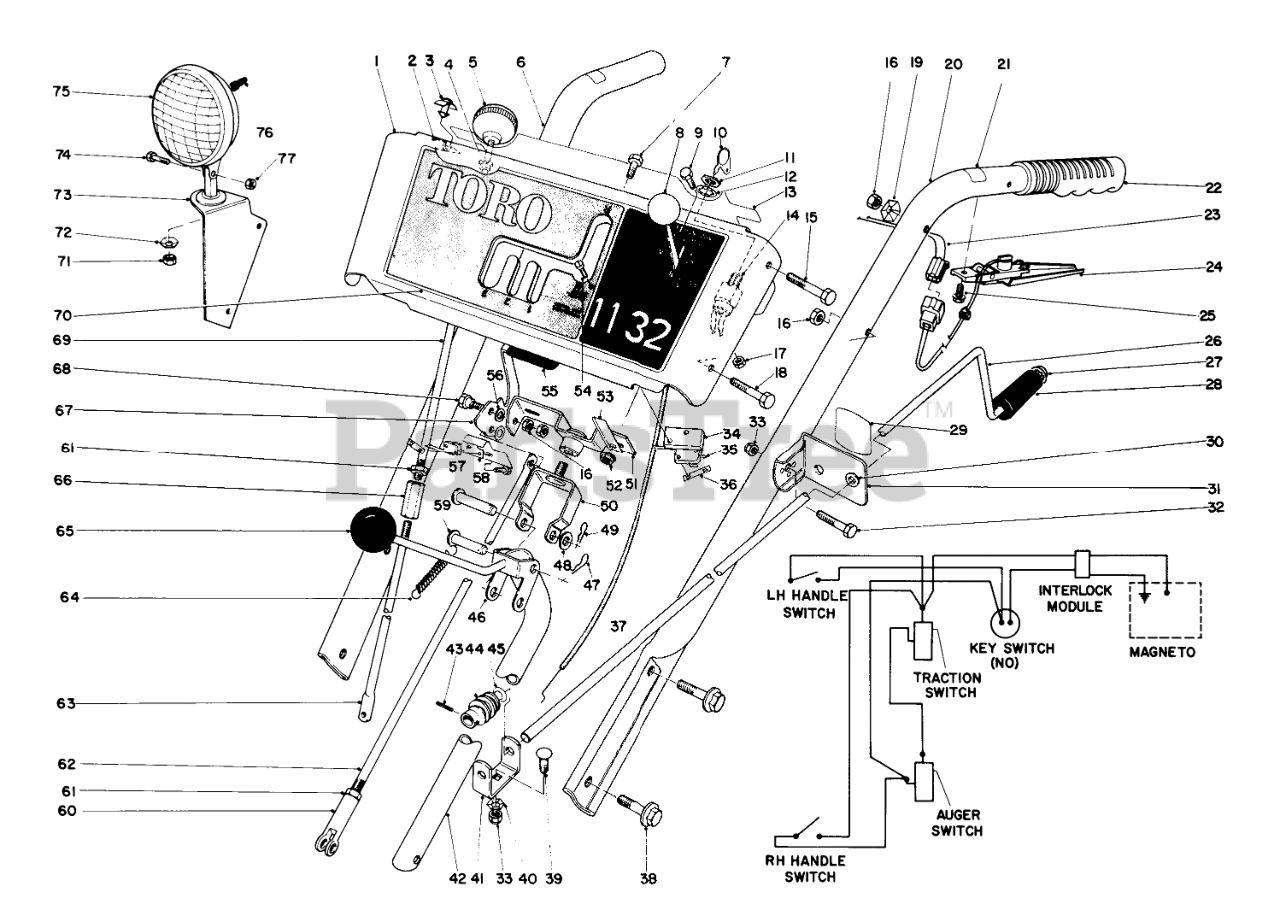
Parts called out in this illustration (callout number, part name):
1	Escutcheon Plate (Incl. Ref. #13 & 70)
2	WIRE CLAMP
3	Mounting Stud
4	NYLINER #6LI-FF TYPE 7
5	KNOB-LEVER
6	Handle Right
7	SCREW-HH
8	CONTROL KNOB
9	HEX HEAD SEMS 10-24X1/2
11	NUT-HH
12	WASHER-TOOTH, INTERNAL
13	BACK ESCUTCH DECAL
14	Key Switch (Incl. Ref. #11 & 12)
15	SCREW-HH
16	NUT-LOCK, CONE
17	NUT-LOCK, NI
18	SCREW-HH
19	Washer
20	HANDLE LEFT
21	INTERLOCK DECAL
22	Grip Handle
23	WIRE HARNESS INTERLOC
24	INTERLOCK HDLE SWITCH
25	SCREW
26	Chute Control Rod
27	RETAINER-PUSH ON
28	GRIP-CONTROL, CHUTE
29	CHUTE DECAL
30	Bushing
31	Bracket-Chute Control Mtg. (Incl. Ref. #29 & 30)
32	SCREW-HH
33	NUT-LOCK, NI
34	SWITCH MTG PAD
35	SWITCH-MICRO
36	NUT-SPEED
37	Throttle Contrl
38	SCREW-HHF
39	BOLT-CARR
40	WASHER-LOCK
41	WORM BRACKET
42	Rod Traction Shift
43	PIN-SPRING
44	GEAR-WORM, CHUTE
45	WASHER-SPRING
46	SHIFT ROD WA
47	PIN-COTTER
48	WASHER-FLAT
49	PIN-HAIR
50	PIVOT BRKT WA
51	SWIVEL BLOCK WA
52	NUT-LOCK, HHF
53	Retainer Wire
54	SCREW-SPH
55	AUGER CLUTCH HND GRIP
56	WASHER-PLAIN
57	PIN-CLEVIS
58	SWITCH BRKT
59	PIN-CLEVIS
60	CLEVIS
61	NUT-HJ
62	DRAG LINK
63	LOWER WHL CLUTCH ROD
64	CONT ROD SPRING 0
66	WHL ROD COUPLING
67	Auger Clutch Handle
68	SCREW-SHOULDER
69	UP WHEEL CLUTCH ROD
70	ESCUTCHEON DECAL
71	NUT-HEX
72	LOCKWASHER-PYRAMID
73	Lamp Mount
74	SCREW-HH
75	HEADLAMP ASM
76	BOOT-SWITCH
77	NUT-HEX, SIDE DEFORM
